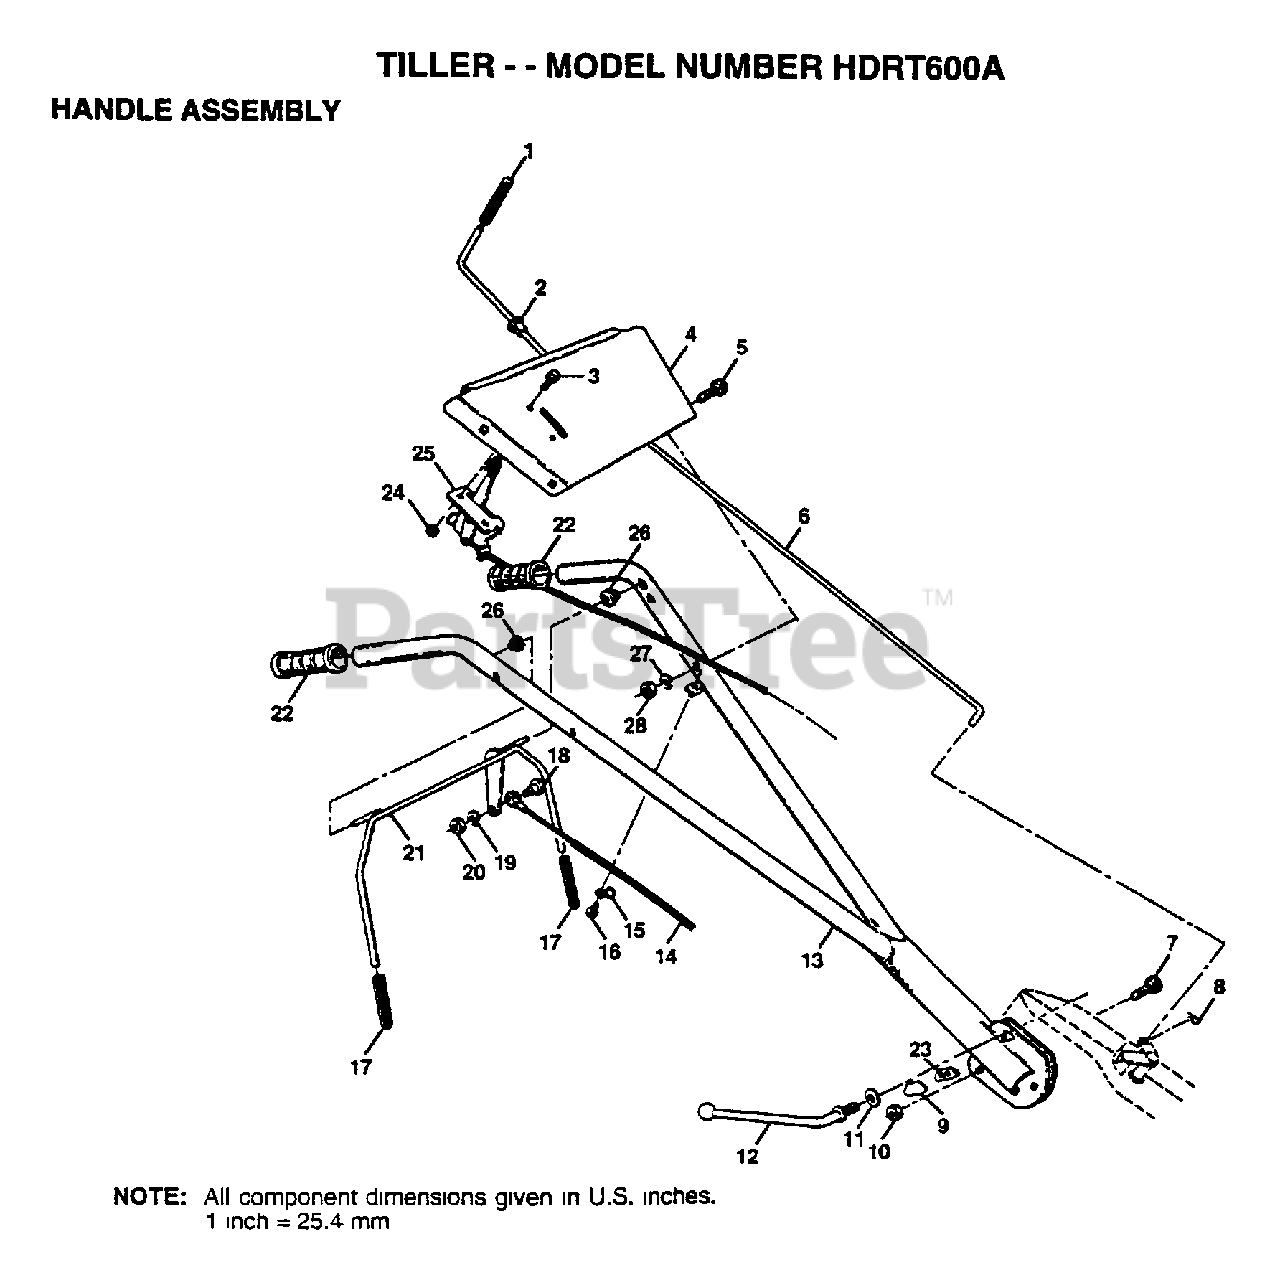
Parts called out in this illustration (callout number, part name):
1	GRIP TI
2	BUSHING
3	SCREW.PNHD.10-24
4	BRACKET.HDLE.TILL
5	BOLT CARRIAGE CRT
6	ROD SHIFT CRT
7	BOLT D
8	RETAINER M
9	LOCK CRT
10	LOCKNUT
11	WASHER CRT
12	LEVER LOCK CRT
14	CABLE-CLUTCH CRT
15	CONDIUT CLIP T
17	GRIP BAR CRT
18	SHOULDER BOLT ST
19	LOCKWASHER
21	HANDLE BAR CRT
22	GRIP HDLE NUBBED
23	LOCK.HANDLE
25	CONTROL.TRTL.6HP.
27	LOCKWASHER
28	NUT
